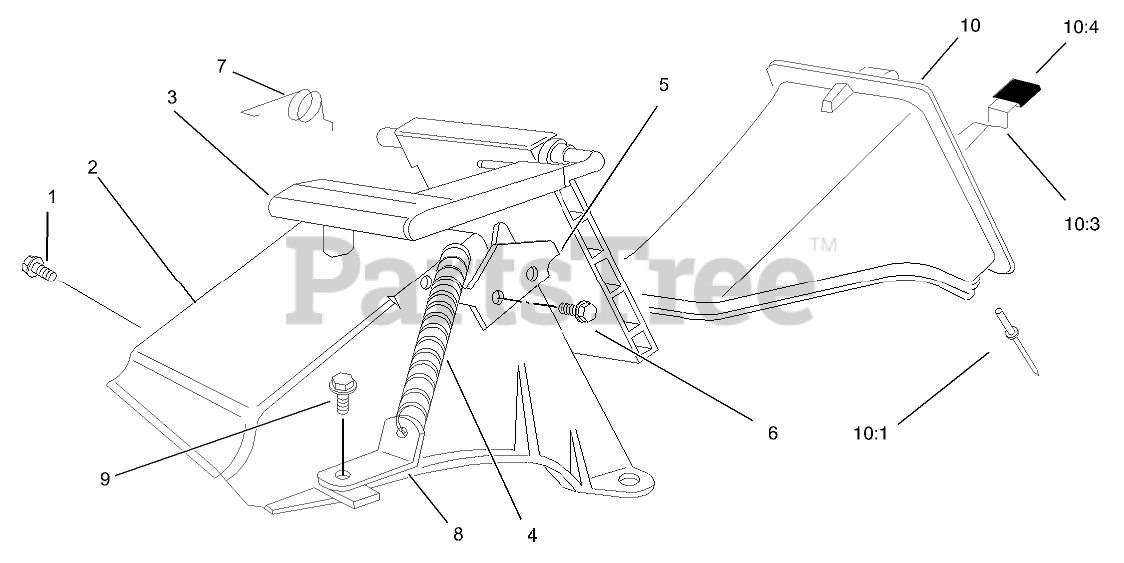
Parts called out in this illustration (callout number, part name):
1	SCREW AND WASHER ASM
2	TUNNEL-DISCHARGE
3	DISCHARGE DOOR ASM
4	SPRING-DOOR
5	LATCH-PLATE
5	PLATE-LATCH
6	SCREW-PLASTITE
7	RETAINER-DOOR
8	BRACKET-SPRING
9	SCREW-HWH
10	DISCHARGE PLUG ASM
10:1	RIVET-HEAD, FLAT
10:3	LATCH-PLUG, DISCHARGE
10:4	GRIP-LATCH
